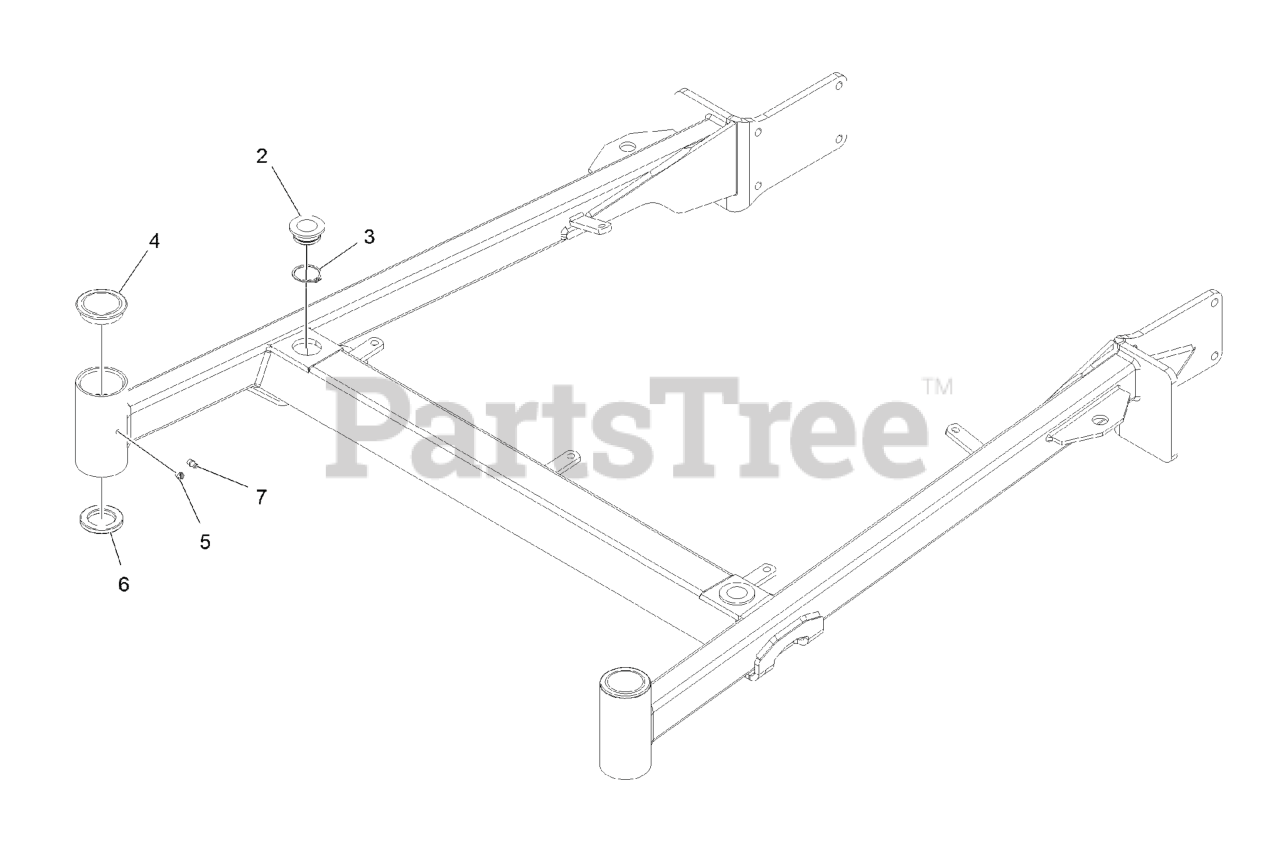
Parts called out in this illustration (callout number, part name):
2	BUSHING-DECK
3	RING-RETAINING
4	CAP-GREASE
6	SEAL-GREASE
7	FITTING-GREASE
